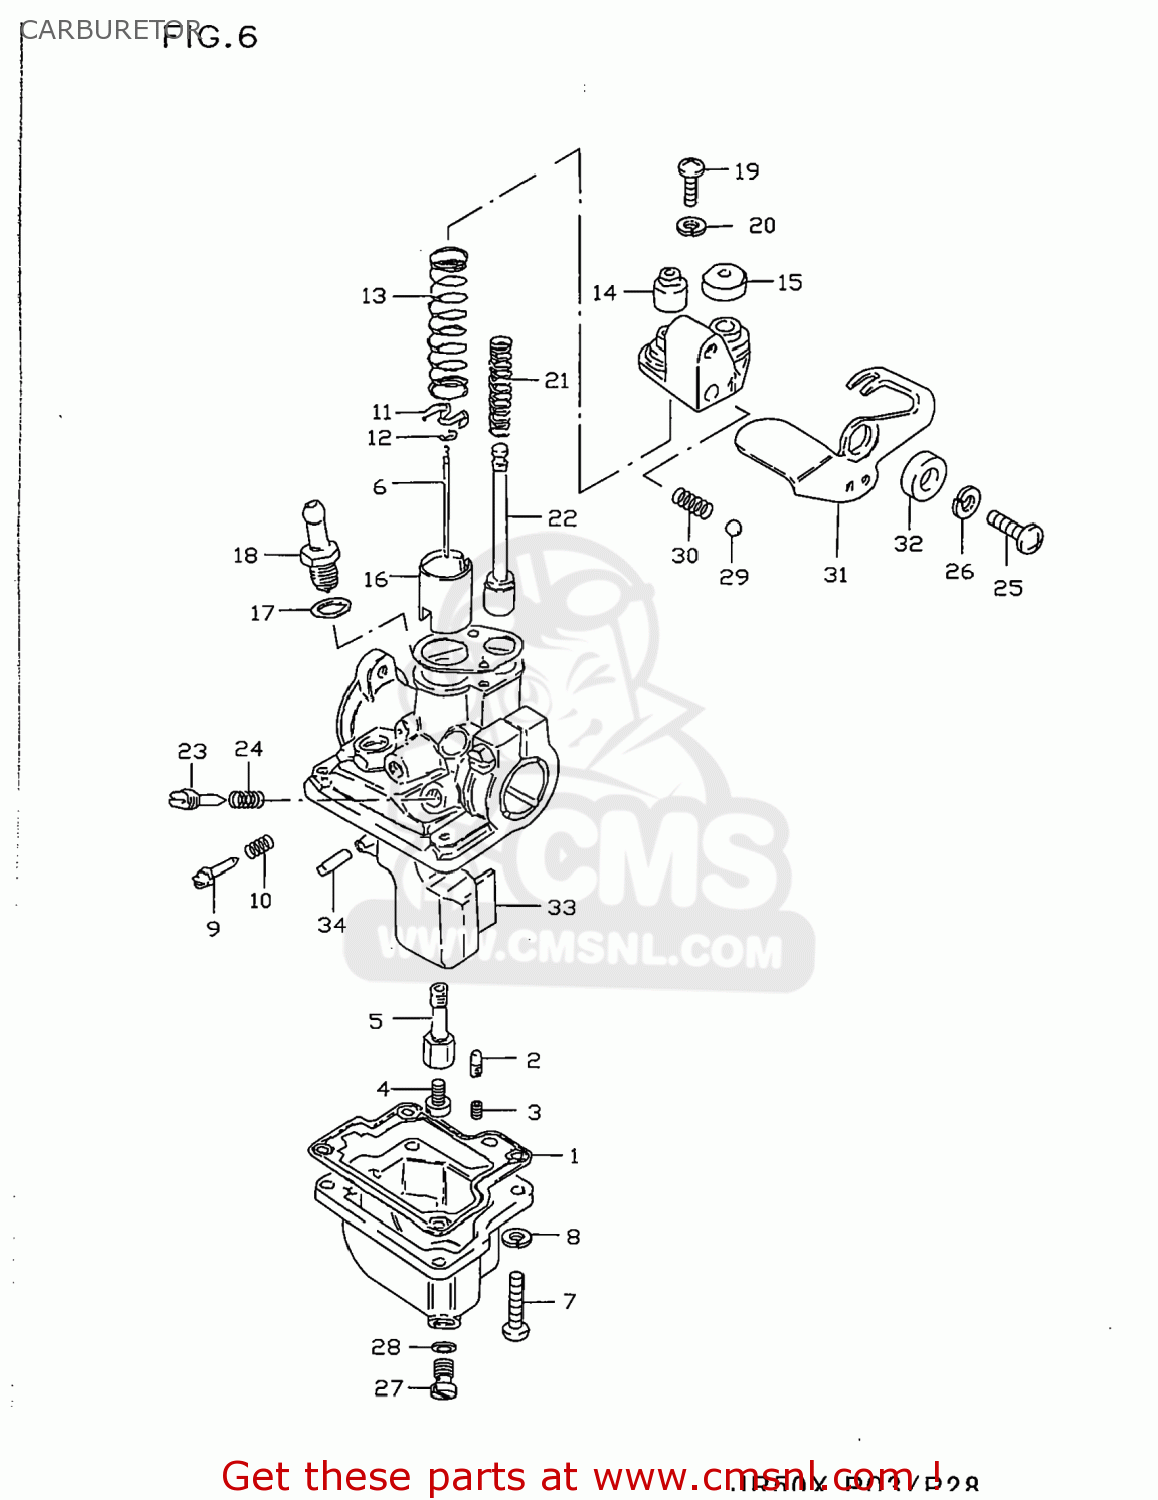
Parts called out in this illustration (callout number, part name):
1	GASKET,FLOAT CAHMBER (NAS)
2	JET,PILOT
3	JET,PILOT
4	JET,MAIN
5	JET,NEEDLE
6	NEEDLE,JET
7	SCREW
8	WASHER,LOCK
9	SCREW,THROTTLE STOP
10	SPRING
11	SEAT,THROTTLE VALVE SPRING
12	CLIP,NEEDLE
13	SPRING,THROTTLE VALVE
14	CAP
15	RUBBER,THROTTLE VALVE CAP
16	VALVE,THROTTLE
17	GASKET,THRO VALVE INSPECTION (NAS)
18	VALVE ASSY,NEEDLE
19	SCREW
20	WASHER,LOCK
21	SPRING
22	VALVE,STARTER
23	SCREW,AIR
24	SPRING
25	SCREW
26	LOCK WASHER
27	PLUG
28	GASKET,DRAIN,PLUG (NAS)
29	BALL,STARTER SHAFT
30	SPRING,STARTER SHAFT
31	LEVER,STARTER
32	RING,CARBURETOR STARTER
33	FLOAT
34	PIN,FLOAT
